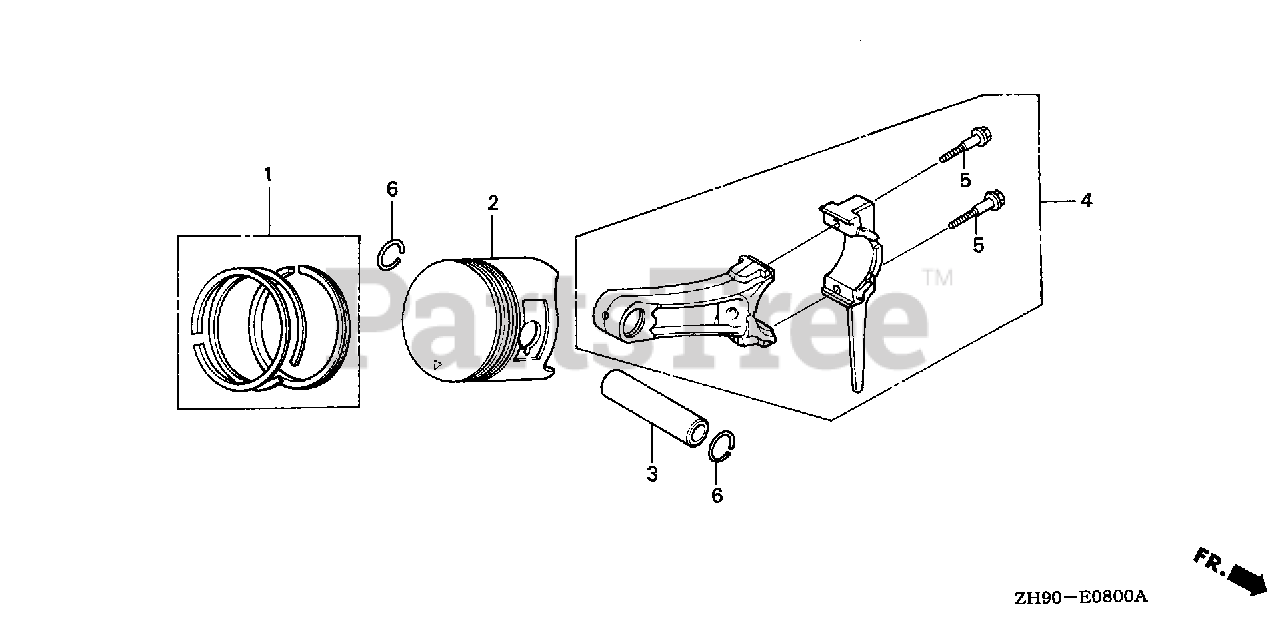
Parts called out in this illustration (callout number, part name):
1	RING SET, PISTON (STD) (NIPPON)
1	RING SET, PISTON (OS 0.25)
1	RING SET, PISTON (OS 0.50)
1	RING SET, PISTON (0.75) (NIPPON)
1	RING SET, PISTON (0.75) (TEIKOKU)
2	PISTON (STD)
2	PISTON (OS 0.25)
2	PISTON (OS 0.50)
2	PISTON (0.75)
3	PIN, PISTON
4	ROD ASSY., CONNECTING (STD)
4	ROD ASSY., CONNECTING (Honda Code 2110153). (US 0.25)
5	BOLT, CONNECTING ROD
6	CLIP, PISTON PIN (18MM)
